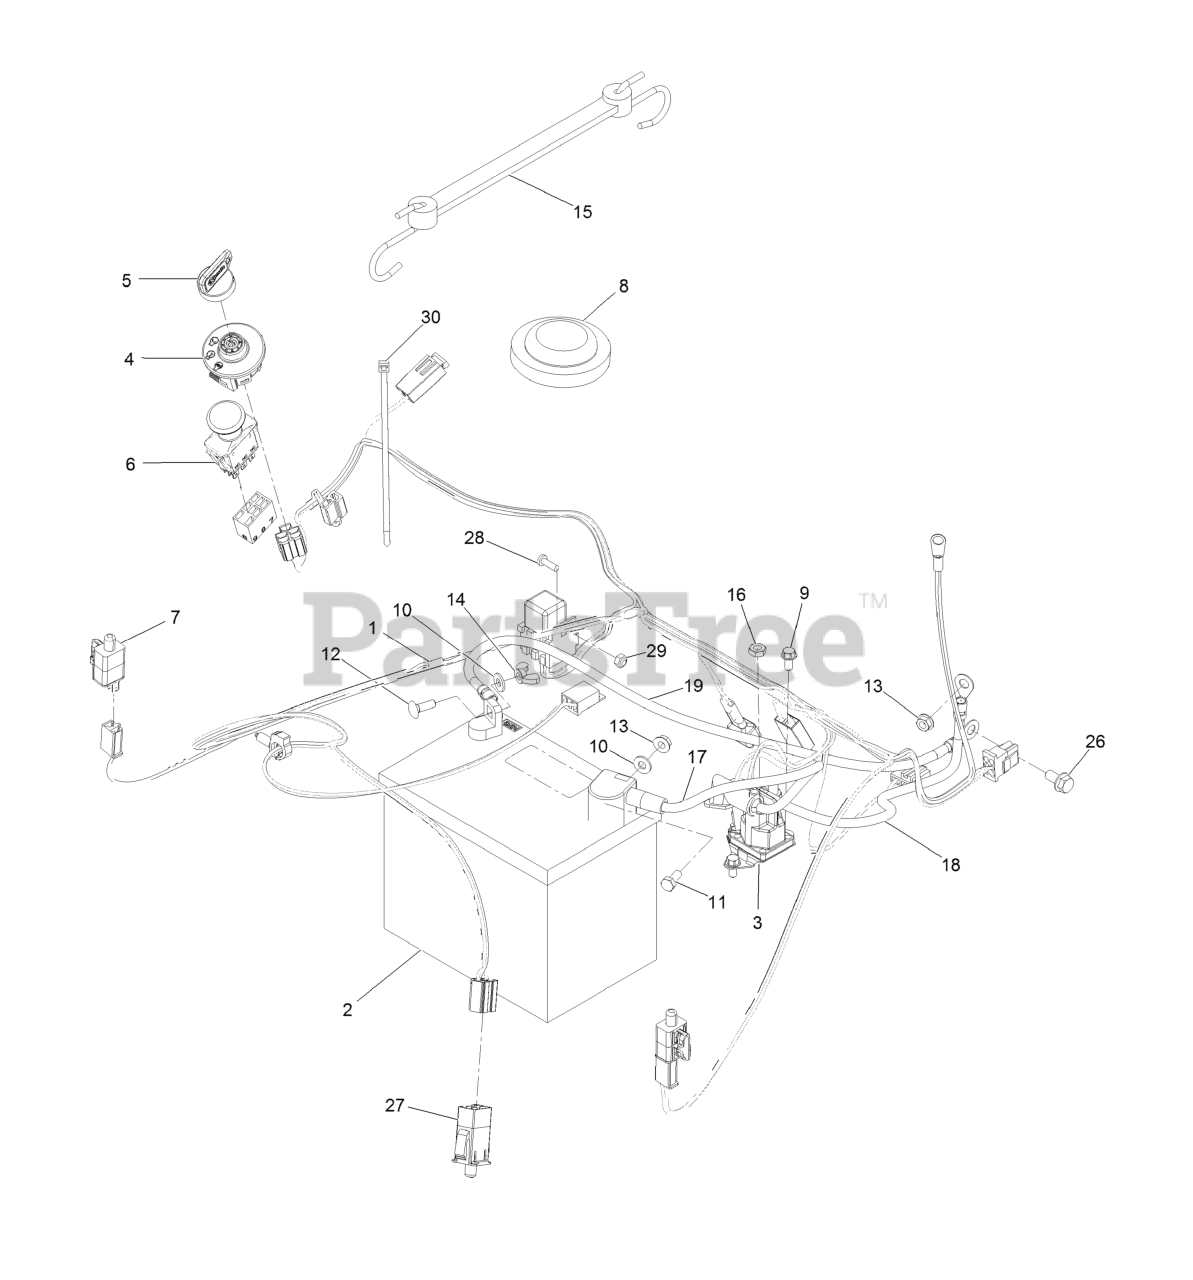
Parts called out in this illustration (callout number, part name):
1	HARNESS-WIRE,
2	BATTERY
3	SOLENOID
4	SWITCH-IGNITION
5	KEY-IGNITION
6	SWITCH-PTO
8	SWITCH-SEAT
9	SCREW-HWH
10	Washer-Flat
11	SCREW-HH
12	BOLT-CARR
14	NUT-WING
15	HOLDDOWN-BATTERY
17	CABLE-BATTERY, RED
18	CABLE-BATTERY, RED
19	CABLE-BATTERY, BLACK
26	SCREW-HHF
27	SWITCH-DELTA
28	SCREW-PPH
29	NUT-LOCK, NI
30	TIE-CABLE
